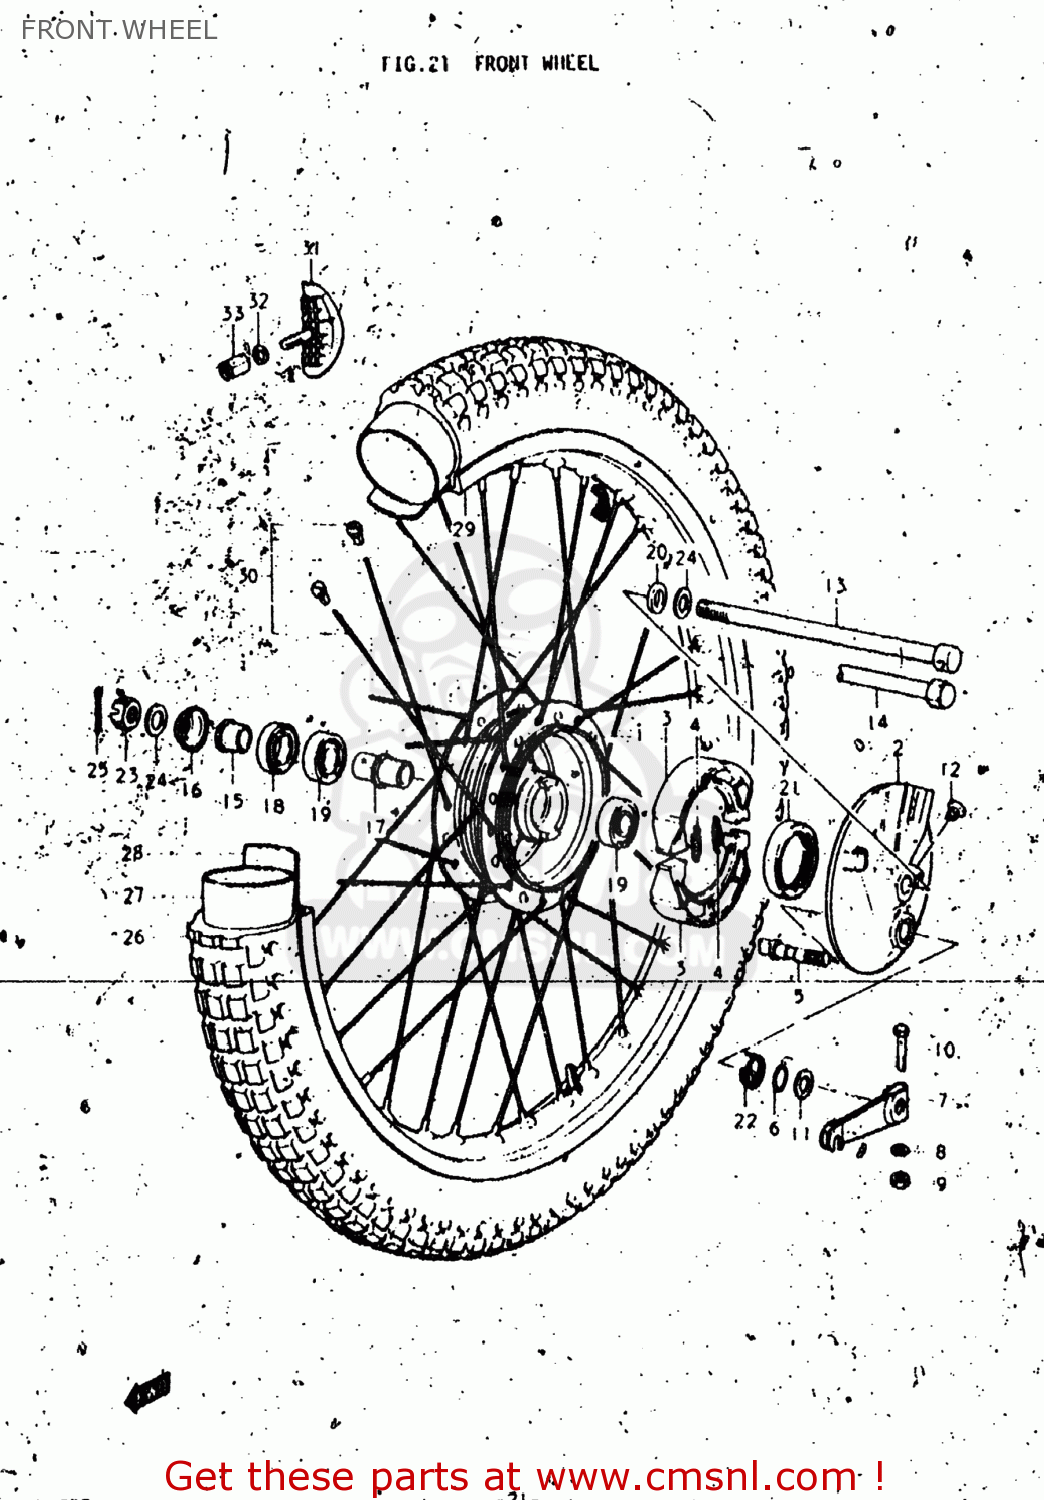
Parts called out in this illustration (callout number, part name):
0	HUB,FRONT
1	HUB,FRONT
2	PANEL,FRONT HUB
3	SHOE,BRAKE
4	SPRING(L:34)
5	CAM,FR BRAKE
6	O RING(D:2.5,ID:11.4)
7	LEVER,FRONT BRAKE CAM
8	WASHER
9	NUT
10	BOLT
11	WASHER(12.5X20X1)
12	CAP(OD:17)
13	AXLE,FRONT
14	AXLE,FRONT
15	SPACER
16	DUST SEAL,FRONT HUB DRUM
17	SPACER
18	OIL SEAL
19	BEARING
20	SPACER
21	OIL SEAL (43X58X7)
22	SPRING
23	NUT 12MM
24	WASHER
25	COTTER PIN
26	TIRE,FRONT
27	TUBE
28	PROTECTOR,WHEEL,INNER
29	RIM,FRONT WHEEL
30	SPOKE SET,FRONT
31	STOPPER,BEAD
32	WASHER
33	NUT
